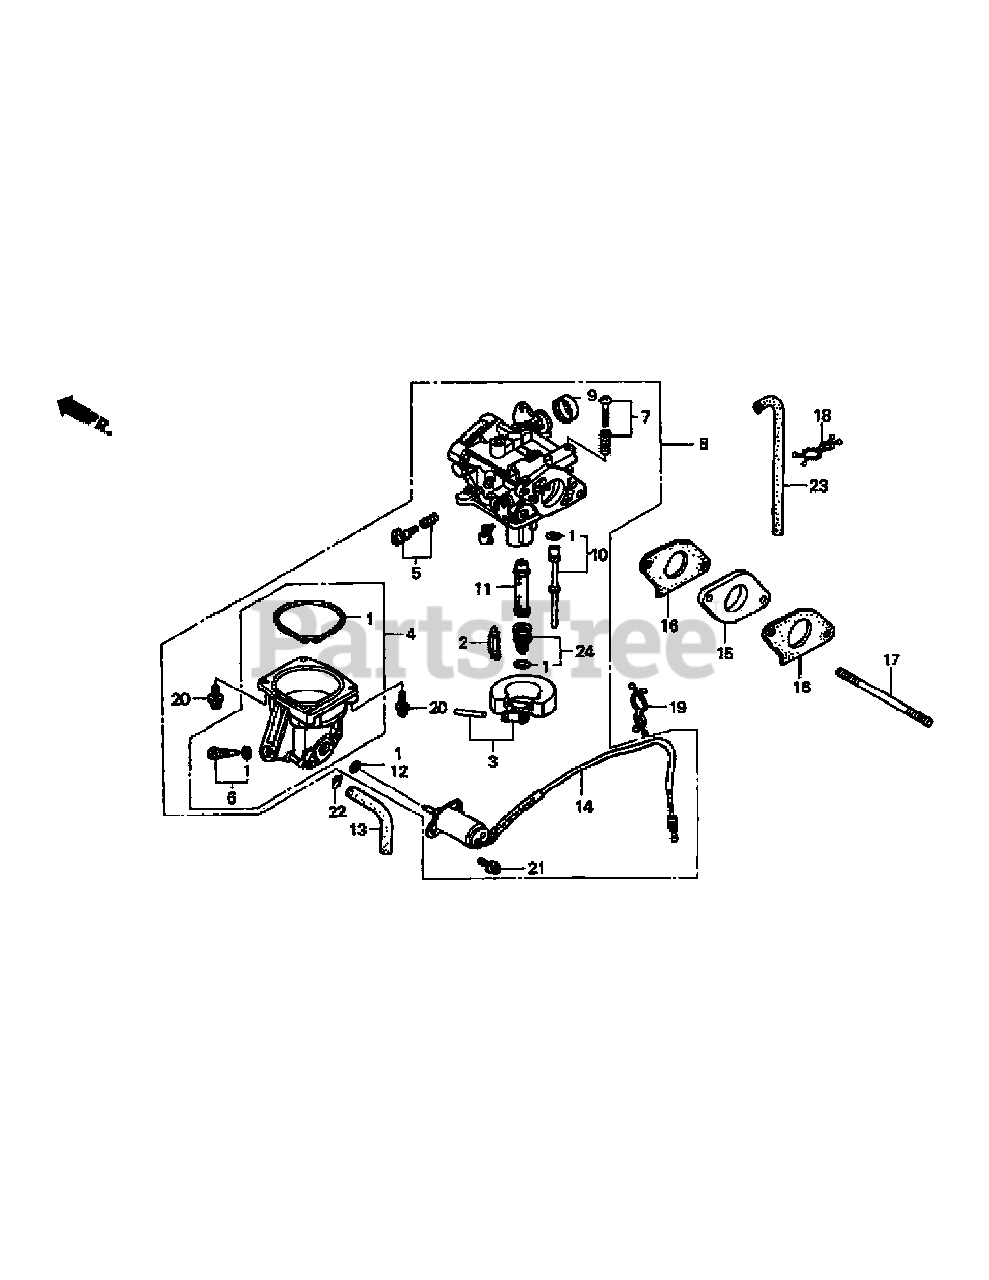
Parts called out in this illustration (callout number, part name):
1	Gasket Set
2	Float Valve Set
4	Float Chamber Set
6	Drain Screw Set
8	Carburetor Assy.
9	Choke Lever Dust Cap
10	Jet Set (#42)
11	Main Nozzle
12	O-Ring (5.8x1.9)
13	Drain Tube
14	Fuel Shut-off Solenoid
15	Carburetor Insulator
16	Carburetor Gasket
17	Stud Bolt (6x100)
18	Wire Harness Clip
19	Purse Lock Clip
20	Screw Washer (4x14)
21	Screw Washer (5x12)
22	Tube Clip
23	Fuel Line (4.5x540)
24	Main Jet Set (#110)
24	Main Jet Set (#112)
24	Main Jet Set (#115)
